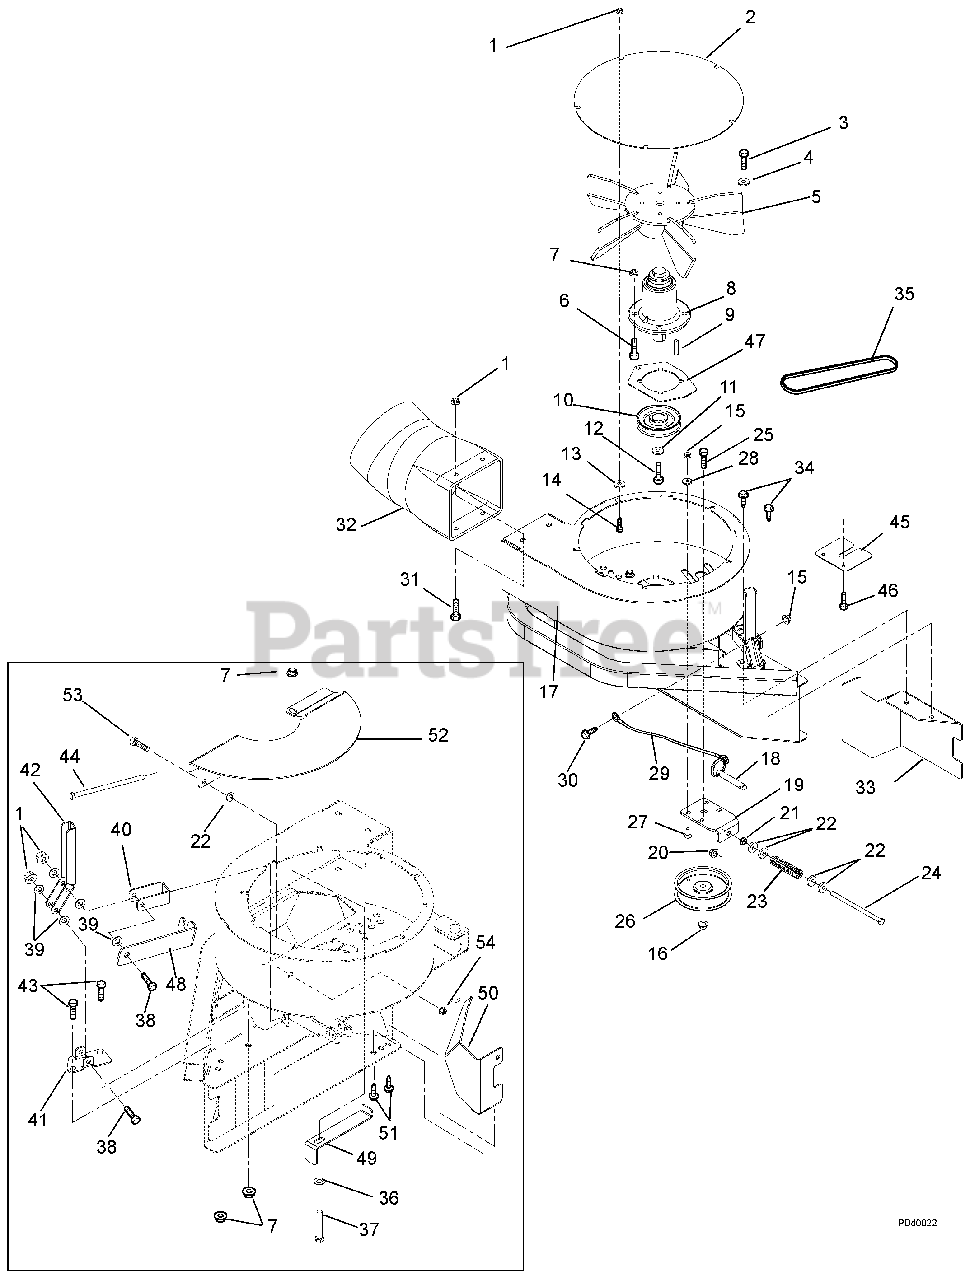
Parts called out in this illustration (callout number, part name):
1	Nut, .31-18 Nyloc Flange
2	Cover, Blower
3	Bolt, Hex .62-18 x 1.75
4	Washer, Bevelled .63 x 1.625 x .14
5	Weldment, Impeller
6	Bolt, Hex .38-16 x 1.25 Grade 5
7	Nut, .38-16 Nyloc Flange
8	Maintenance Free Spindle Assembly
9	Key, Square .25 x .25 x 1.00 RC 40-50
10	Weldment, Pulley-V 3.50 x 1.004 with Key
11	Washer, Flat Steel .39 x 1.5 x .125
12	Bolt, Hex .38-16 x 1.00 EP30
13	Nut, Push .312
14	Bolt, Round Head Square Short Neck .31-18 x .75 Grade 5
15	Nut, Locking Top Flange .25-20
16	Nut, .38-16 Nyloc Flange
17	Weldment, Blower Housing
18	Pin, Spring Ball .375OD x 1.50
19	Bracket, Adjustable Idler
20	Nut, .31-18 Nyloc Flange
21	Nut, Spin Lock-Flange .312-18
22	Washer, Flat Steel .38 x .87 x .179
23	Spring, Compression .092 x .77 x 3.13
24	Bolt, Hex .31-18 x 5.50 Grade 5
25	Bolt, Hex .38-16 x 1.75 Grade 5
26	Pulley, Idler 4.00
27	Bolt, Round Head Square Neck .25-20 x .75 Grade 5
28	Bushing, Flange .265 x .437 x .250 x .750
29	Cable, Hood
30	Bolt, Hex .25-20 x .75 Grade 5
31	Bolt, Hex .31-18 x .75 Grade 5
32	Adapter, Hose
33	Baffle, Blower 52"
34	Screw, Tapping .38-16 x .50 Hex Washer Head
35	V-Belt, 72" Mower Deck
36	Washer, Flat Steel .406 x .812 x .065
37	Bolt, Hex .38-16 x 1.00 Grade 5
38	Bolt, Hex .31-18 x 2.00 Grade 5
39	Washer, Flat – Nylon .375 x .75 x .060
40	Link, Idler Release
41	Mount, Idler Release Lever
42	Lever, Idler Release
43	Bolt, Hex .38-16 x .75 Grade 5
44	Bolt, Hex .31-18 x 5.50 Grade 5
45	Finger Guard 52-Inch Deck
46	Bolt, Hex .25-20 x .50 Grade 5
47	Plate, Bearing Housing Support
48	Lock, Idler Release Lever
49	Finger – Belt
50	Baffle, Blower – Rear – 52"/60"/66"
51	Screw, Tap .38-16 x .50
52	Cover, Bottom Plate
53	Bolt, Hex .31-18 x 0.75
54	Nut, Nyloc Flange .31-18
